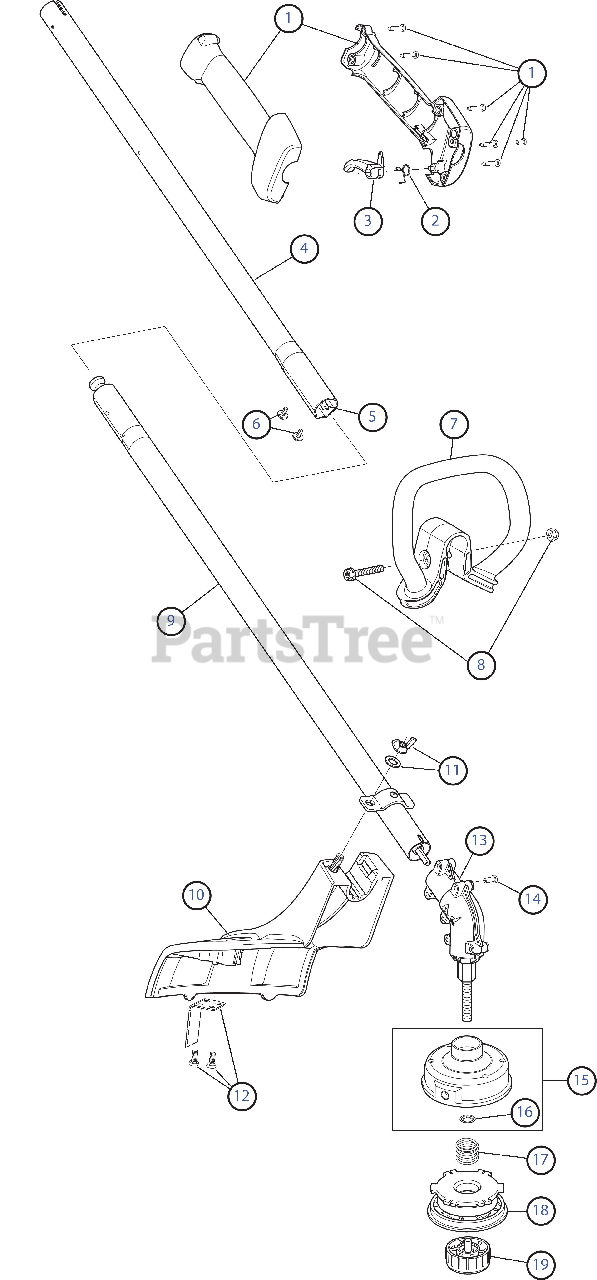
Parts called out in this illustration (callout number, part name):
1	Throttle Housing Assembly (Incl. 2 & 3)
2	Throttle Trigger Spring
3	Throttle Trigger
4	Upper Shaft Housing Assembly (Incl. 5)
5	Upper Flexible Drive Shaft
7	D-Handle (Incl. 8)
8	D-Handle Bolt
9	Lower Shaft Housing Assembly
10	Shield Assembly (Incl. 11 & 12)
11	Shield Mounting Hardware
12	Blade Assembly
13	Gearbox Assembly (Incl. 14 - 19)
14	Anti-Rotation Screw
15	Outer Spool Assembly (Incl. 16)
16	Retainer
18	Inner Reel
19	Bump Head Knob Assembly
